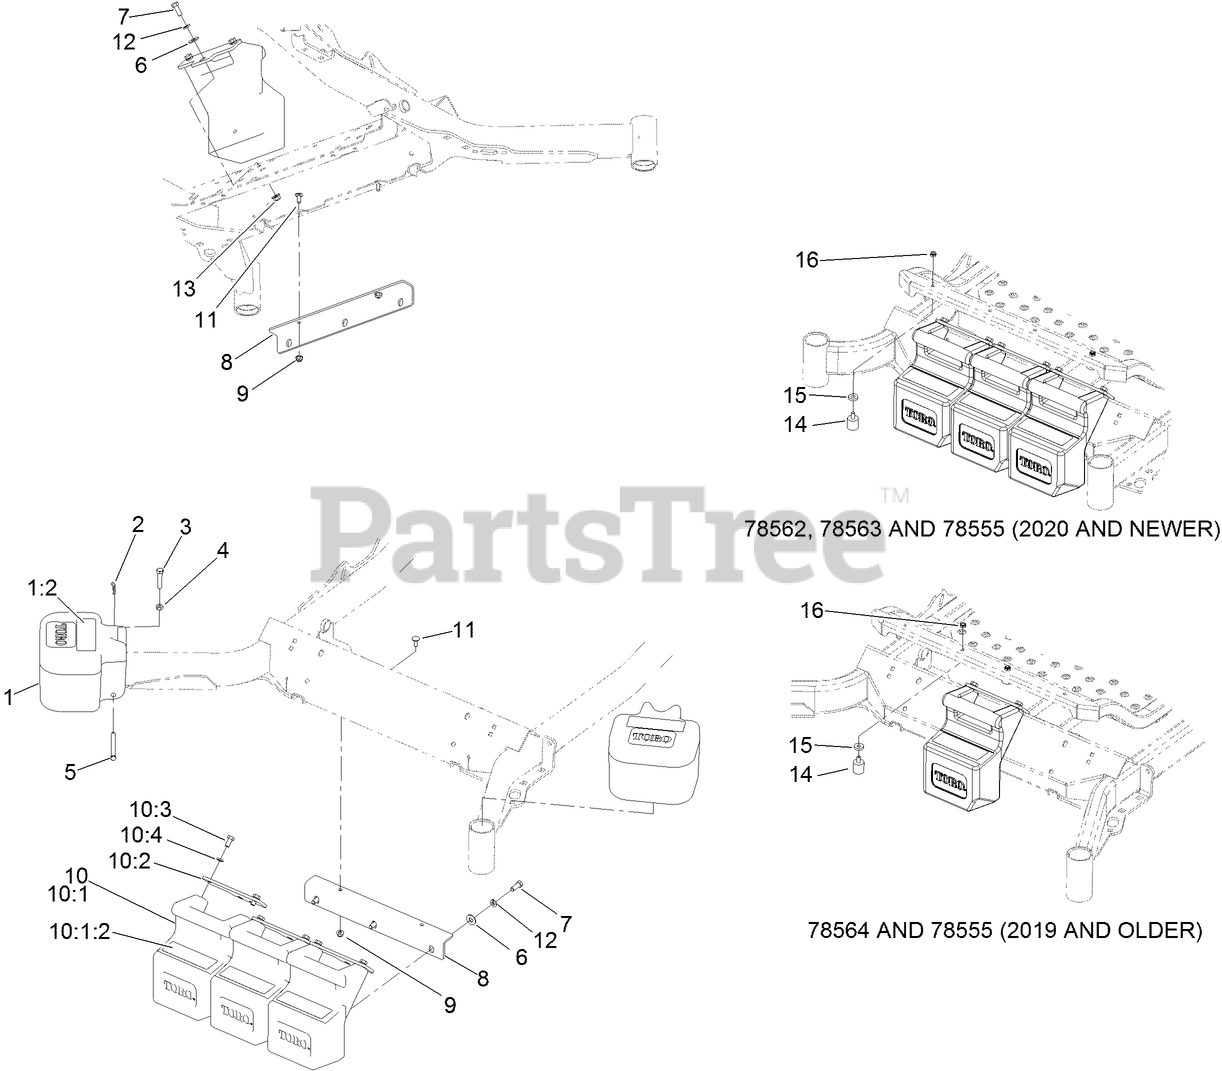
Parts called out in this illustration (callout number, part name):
1	WEIGHT 62 LBS ASM W/DECAL
1:2	DECAL-WARNING, COUNTERWEIGHT
2	PIN-COTTER
3	SCREW-HH
4	NUT-HEX
5	PIN-CLEVIS
6	WASHER-FLAT
7	SCREW-HH
8	BRACKET-MOUNT, WEIGHT
9	NUT-HF, NI
10	WEIGHT ASM
10:1	WEIGHT W/DECAL ASM
10:1:2	DECAL-WARNING, COUNTERWEIGHT
10:2	TAB-SUPPORT, WEIGHT
10:3	SCREW-HH
10:4	WASHER-LOCK
11	SCREW-CARR
12	WASHER-LOCK
13	NUT-HF, NI
14	BUMPER-RUBBER
15	SPACER
16	NUT-LOCK, NI
